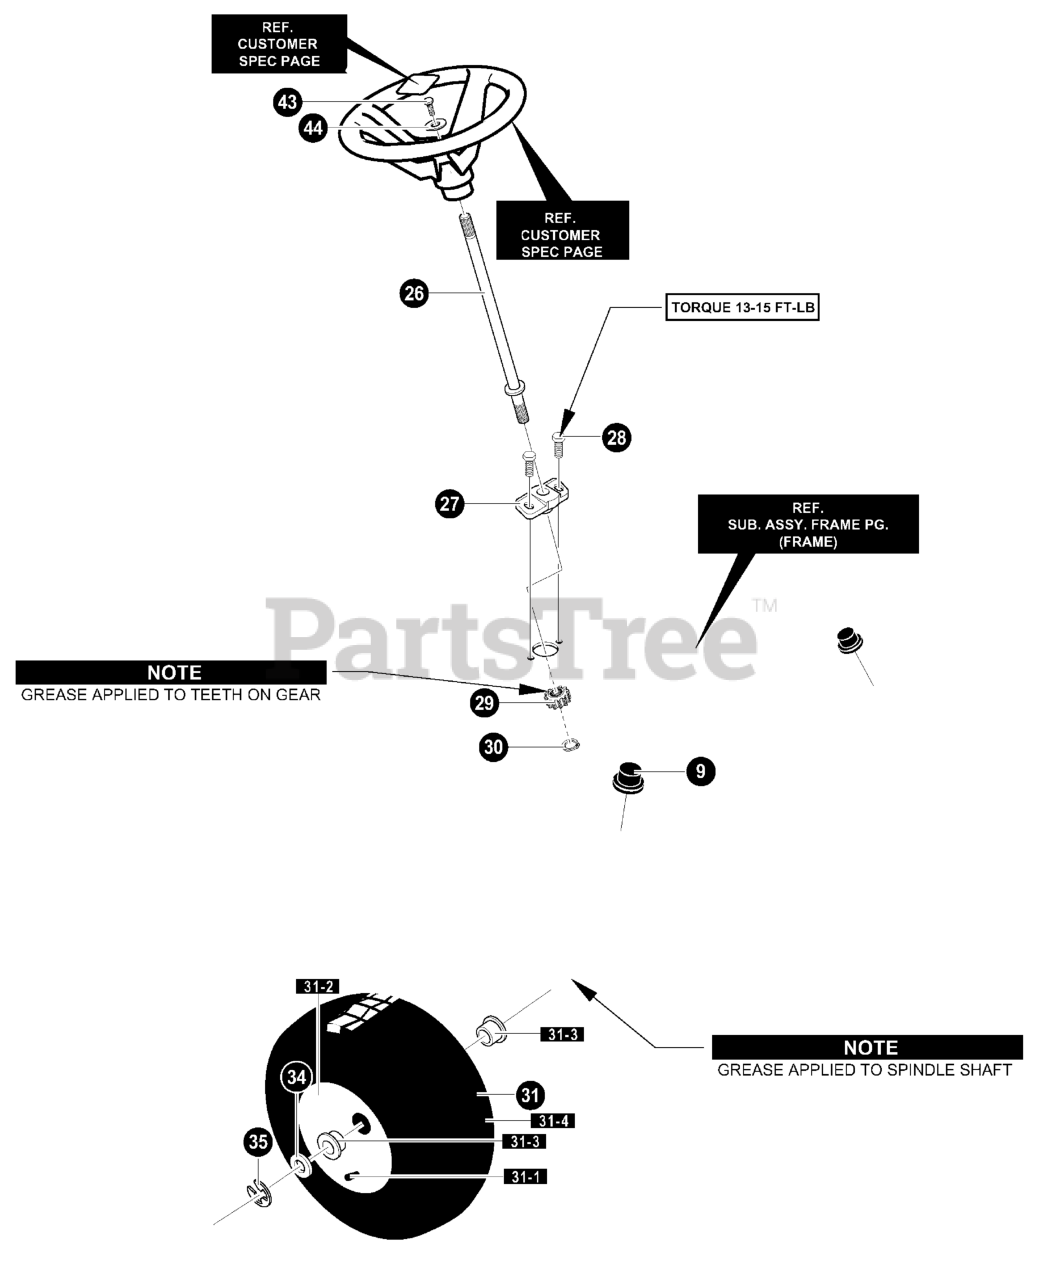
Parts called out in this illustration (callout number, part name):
9	DUST HUB CAP
26	SHAFT, STEERING
27	BEARING-LOWER
28	SCREW, 5/16-18 x 0.75
29	GEAR PINNION
30	RING, RET E.
31	TIRE & RIM, 15X6.0-6
31-1	VALVE STEM
31-3	BEARING
31-4	TIRE, 15X6X6
34	WASHER, FLAT .765 x 1.81 x .059
35	E-RING
43	SCREW, 1/4-20X.75 HHC
44	WASHER, FLAT .281X1.25X.06
